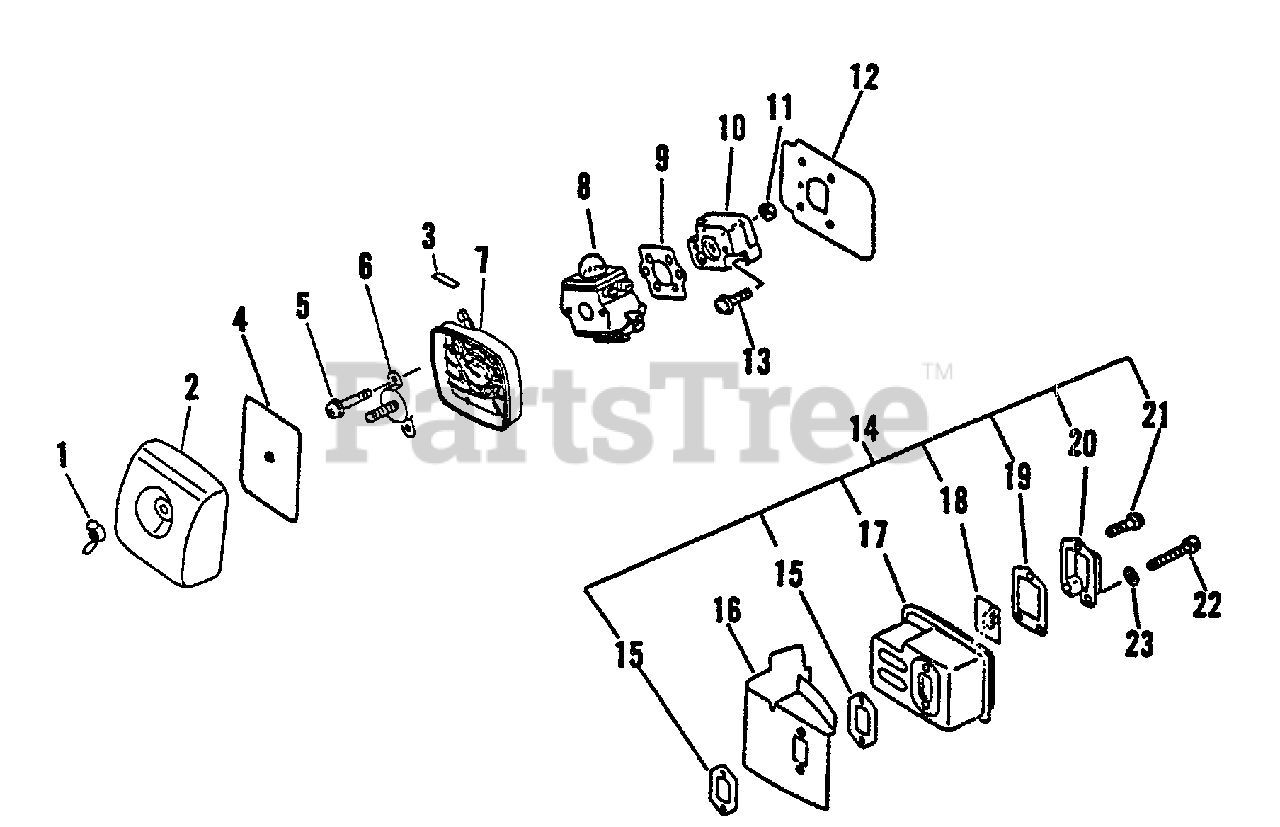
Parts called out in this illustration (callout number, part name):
1	WINGNUT - 6
2	COVER, AIR FILTER - BLACK
3	LABEL - CHOKE
4	FILTER, AIR
5	SCREW - 5X65
6	PLATE, PREVENT
7	AIR FILTER CASE ASSY
8	CARBURETOR C1U-K27B
9	GASKET, INTAKE
10	INSULATOR, INTAKE
12	SHIELD, INTAKE
13	SCREW - 5X20
14	MUFFLER ASSY
15	GASKET, EXHAUST
16	SHIELD, EXHAUST
18	SCREEN, SPARK ARRESTOR
19	GASKET, EXHAUST
20	GUIDE, EXHAUST - OUTER
21	SCREW - 4X10
22	SCREW - 5X50
23	WASHER - 5
